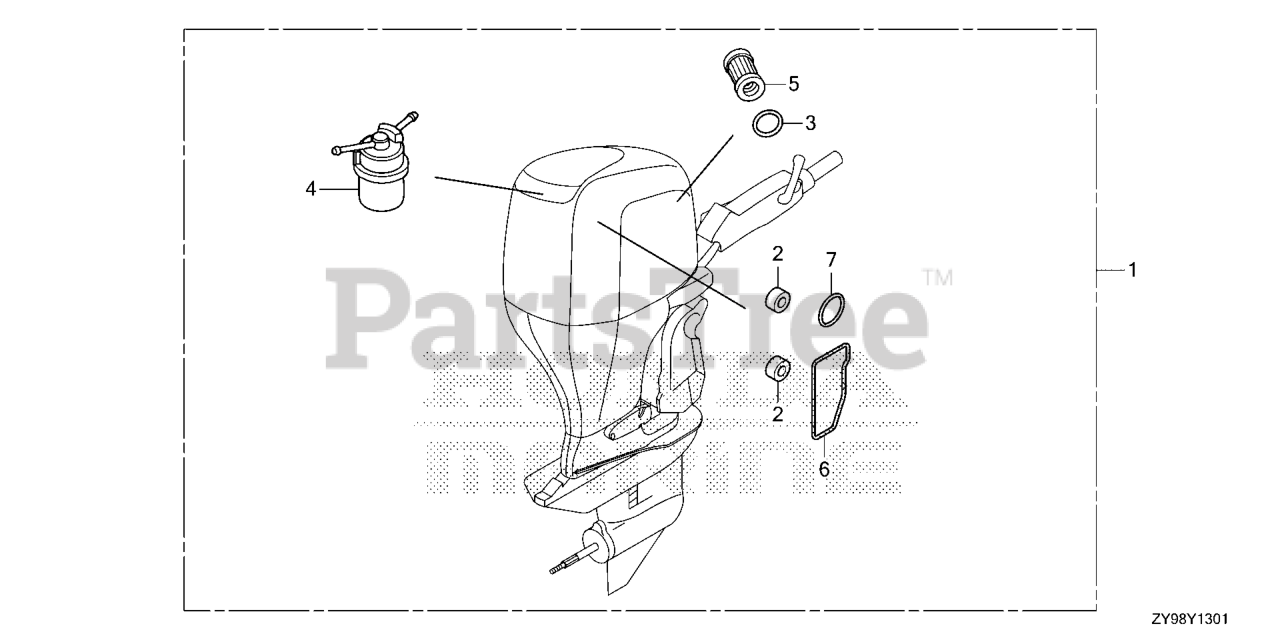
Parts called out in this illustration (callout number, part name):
1	KIT (400)
2	METAL, ANODE
3	O-RING
4	FILTER, FUEL
5	SCREEN, FUEL STRAINER
6	GASKET, REGULATOR
7	O-RING (33X2.4)
